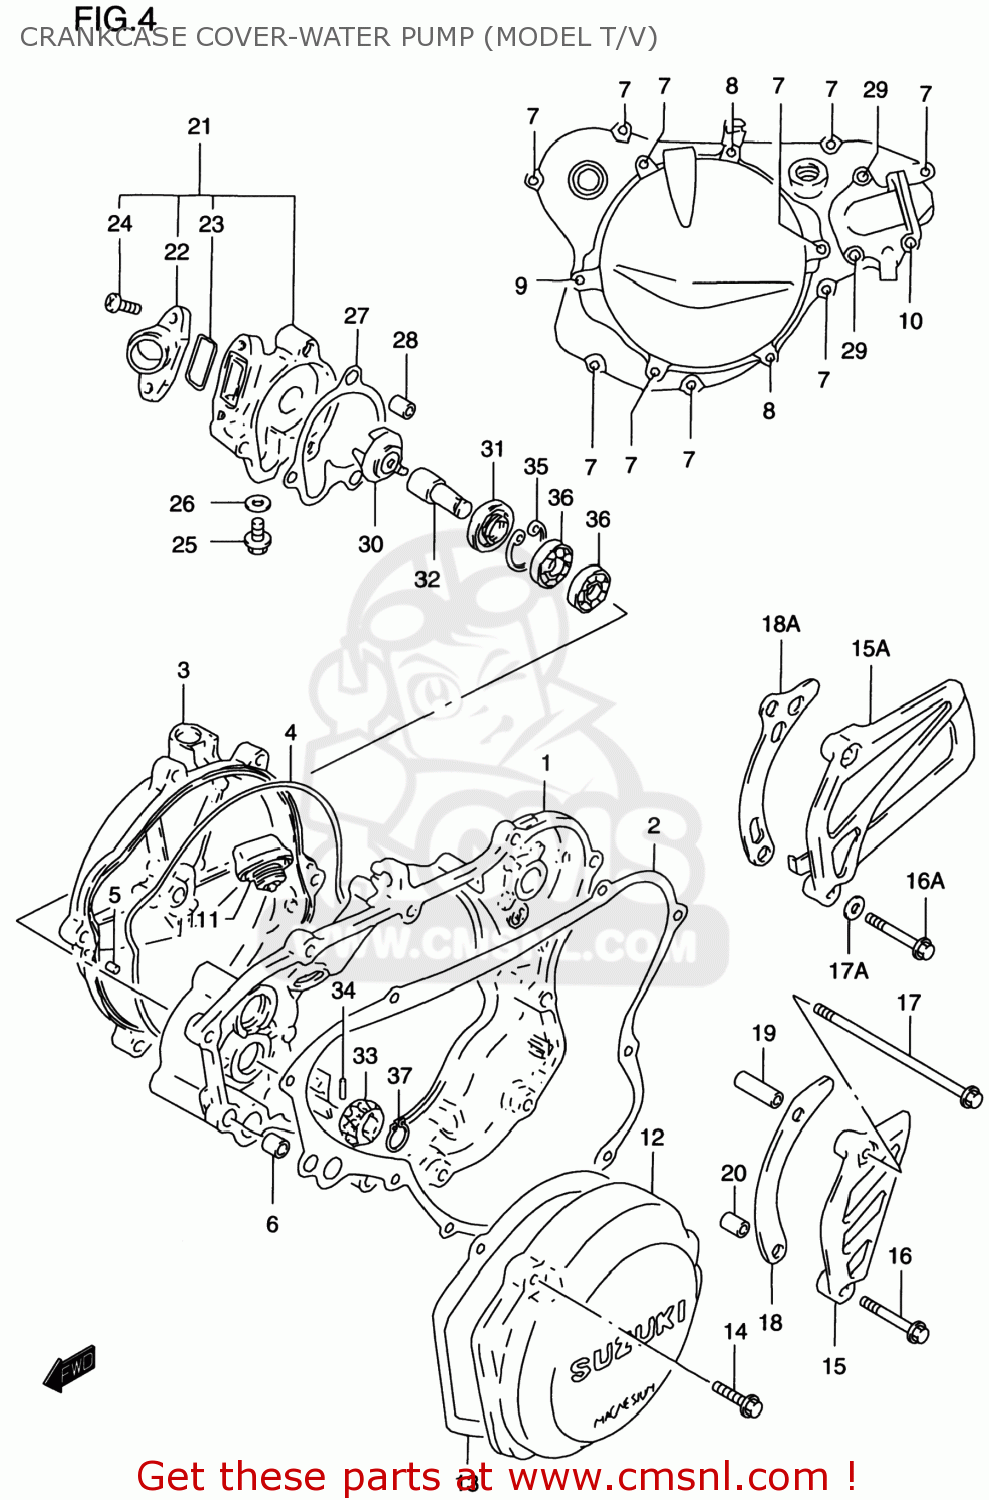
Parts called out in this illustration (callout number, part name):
1	COVER SET,CLUTCH
2	GASKET,CLUTCH COVER (NAS)
3	COVER,CLUTCH OUTER
4	O RING,CLUTCH COVER OUTER
5	PIN
6	PIN
7	SCREW
8	BOLT
9	BOLT
10	BOLT(6X100)
11	PLUG SET
12	COVER,MAGNETO
13	GASKET,MAGNETO COVER (NAS)
14	SCREW
15	COVER,ENGINE SPROCKET
15A	COVER,ENGINE SPROCKET
16	BOLT
16A	BOLT,G/S SWITC
17	BOLT(6X100)
17A	WASHER (6.2X14X2)
18	PLATE,FR CHAIN GUIDE
18A	PLATE,FR CHAIN GUIDE
19	SPACER(6.5X10.5X25)
20	SPACER(6.5X10.5X12)
21	CASE ASSY,WATER PUMP
22	CONNECTOR
23	O RING,WATER PUMP CONNECTOR
24	SCREW 6X16
25	BOLT
26	WASHER
27	GASKET,WATER PUMP CASE (NAS)
28	PIN
29	BOLT
30	IMPELLER,WATER PUMP
31	SEAL,WATER PUMP OIL
32	SHAFT,WATER PUMP
33	GEAR,WATER PUMP DRIVEN(NT:22)
34	PIN(3X13.8)
35	CIRCLIP
36	BEARING
37	CIRCLIP,10MM
